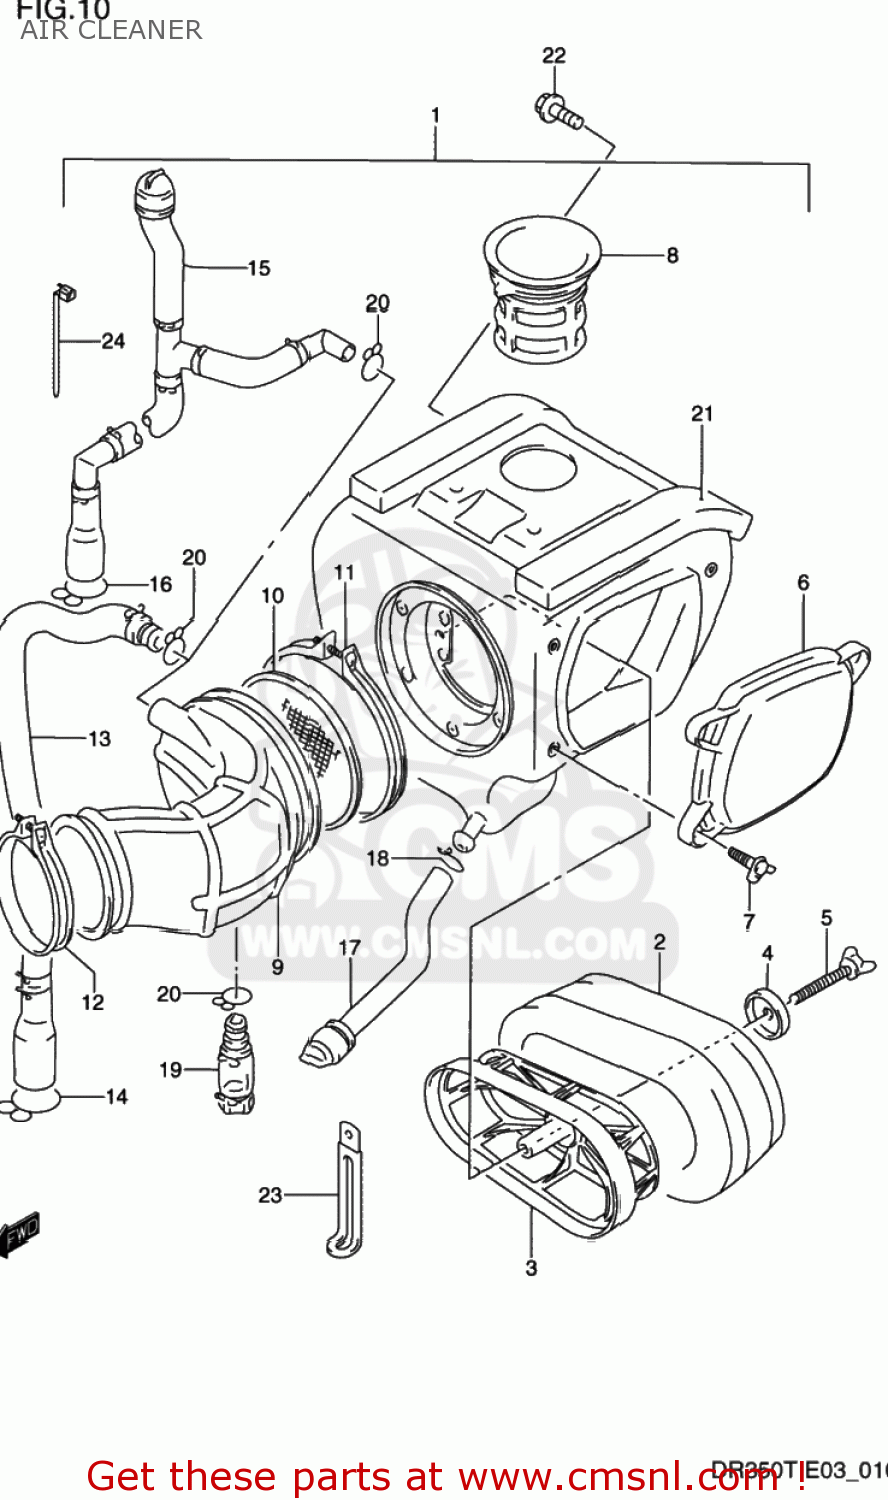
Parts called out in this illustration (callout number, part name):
1	CLEANER ASSEMBLY,AIR
2	FILTER
3	HOLDER,FILTER
4	WASHER,AIR CLEANER
5	BOLT,WING
6	CAP,AIR CLEANER
7	BOLT,WING
8	TUBE,INLET
9	TUBE,OUTLET
10	TRAP,FRAME
11	CLAMP
12	CLAMP
13	TUBE,BREATHER
14	CLIP
15	TUBE,BREATHER
16	CLIP
17	DRAIN TUBE
18	CLIP
19	TUBE,DRAIN
20	CLIP
21	CUSHION
22	BOLT
23	CLAMP
24	CLAMP L:165
